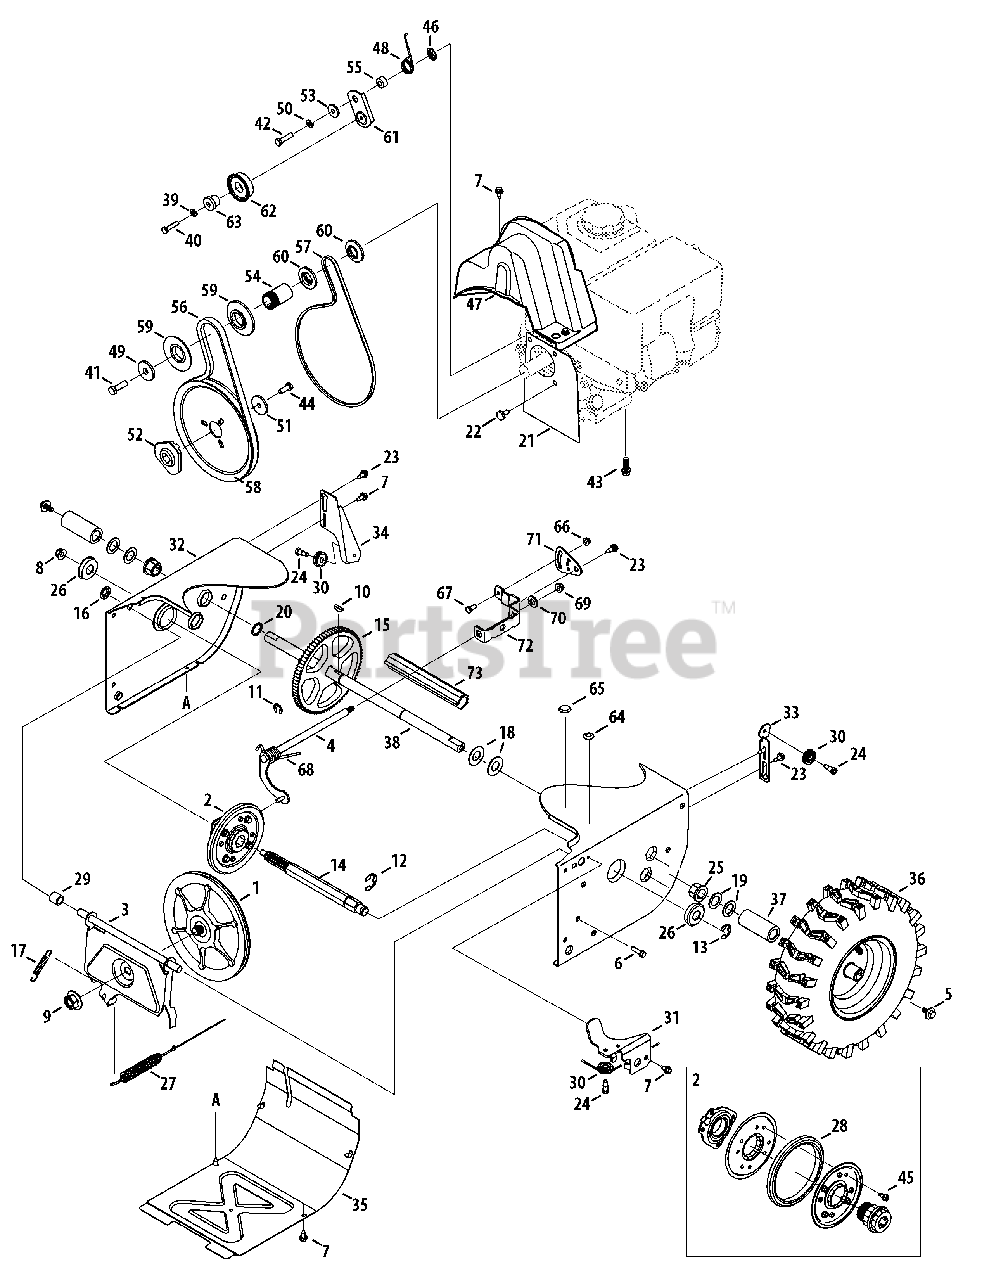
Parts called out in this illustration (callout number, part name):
1	Disc Assembly, Friction Wheel
2	Friction Wheel Assembly, 5.5 OD
3	Support Bracket, Friction Wheel
4	Shift Assembly, Rod
5	Screw, 5/16-24, .750, Gr5
6	Screw, 1/4-20, 1.000
7	Screw, 1/4-20 x .625
8	Nut, Flange Lock, 3/8-16, Nylon
9	Nut, Flange, 5/8-18
10	Key, Hi Pro, 3/16 x 3/4 Dia.
11	E-ring, .500 Dia.
12	E-ring, Retaining, .875 Dia.
13	E-ring, .750 Dia.
14	Hex Shaft, .8125, 7-Tooth
15	Gear, 80-Tooth
16	Speed Nut, .500
17	Extension Spring
18	Washer, Flat, .760 x 1.490 x .060
19	Washer, Flat, .793 x 1.24 x .060
20	Washer, Flat, .75 x 1.00 x .060
21	Plate, Cover
22	Shoulder Screw
23	Screw, Shoulder, .37 x .105, 1/4-20
24	Screw, 1/4-28, .375
25	Bearing, Hex Flange x .75 ID
26	Bearing, Ball, 17 x 40 x 12
27	Clutch Cable, Wheel, 44.95"
28	Rubber, Friction Wheel, 5.5 OD
29	Spacer, .508 ID x .75 OD x .68
30	Roller, Cable
31	Front Guide Bracket, Auger Cable
32	Frame
33	Guide Bracket, Auger Cable
34	Guide Bracket, Drive Cable
35	Cover, Frame
36	LH Wheel Assembly
36	RH Wheel Assembly
37	Spacer, 1.25 x .75 x 3.0
38	Axle, .75 x 22"
39	Washer, Lock, 1/4
40	Hex Screw, 1/4-20, 1.25, Gr5
41	Hex Screw, 3/8-24, 1.25, Gr8
42	Hex Screw, 5/16-24, 1.25, Gr5
43	Screw, Sems, 3/8-16, 1.00
44	Hex Screw, 5/16-24, .875, Gr8
45	Screw, 5/16-18 x .750
46	Nut, Push-on, .25 Dia.
47	Cover, Belt
48	Spring, Torsion, .850 ID x .354
49	Washer, Flat, .45 x 1.5 x .172
50	Washer, Lock .3125
51	Washer, Flat, .34 x 1.50 x .150
52	Pulley, Adapter, .75 Dia.
53	Spacer, Shoulder, .317 x .50 x .102
54	Spacer, .875 ID x 1.185 OD
55	Spacer, .340 x .750 x .360
56	Belt, Auger Drive
57	Belt, Wheel Drive
58	Pulley, Auger Drive, 8.1 x .5
59	Pulley, Half, V x 2.600 OD
60	Pulley, Half, 3/8-V x 1.7160 OD
61	Idler Bracket, Wheel Drive
62	Idler Pulley Assembly
63	Spacer, Shoulder, .26 x .79 x .538
64	Plug, 3/8 ID
65	Plug, 1/2 ID
66	Nut, Flange Lock, 1/4-20, Nylon
67	Hex Screw, 1/4-20, .620, Gr5
68	Spring, Torsion, .750 ID x .968
69	Nut, Flange Lock, 5/16-18, Nylon
70	Wash., Flat, .469 x .875 x .105
71	Pivot Bracket, Speed Selector
72	Shift Bracket, Speed Selector
73	Spacer, Axle
